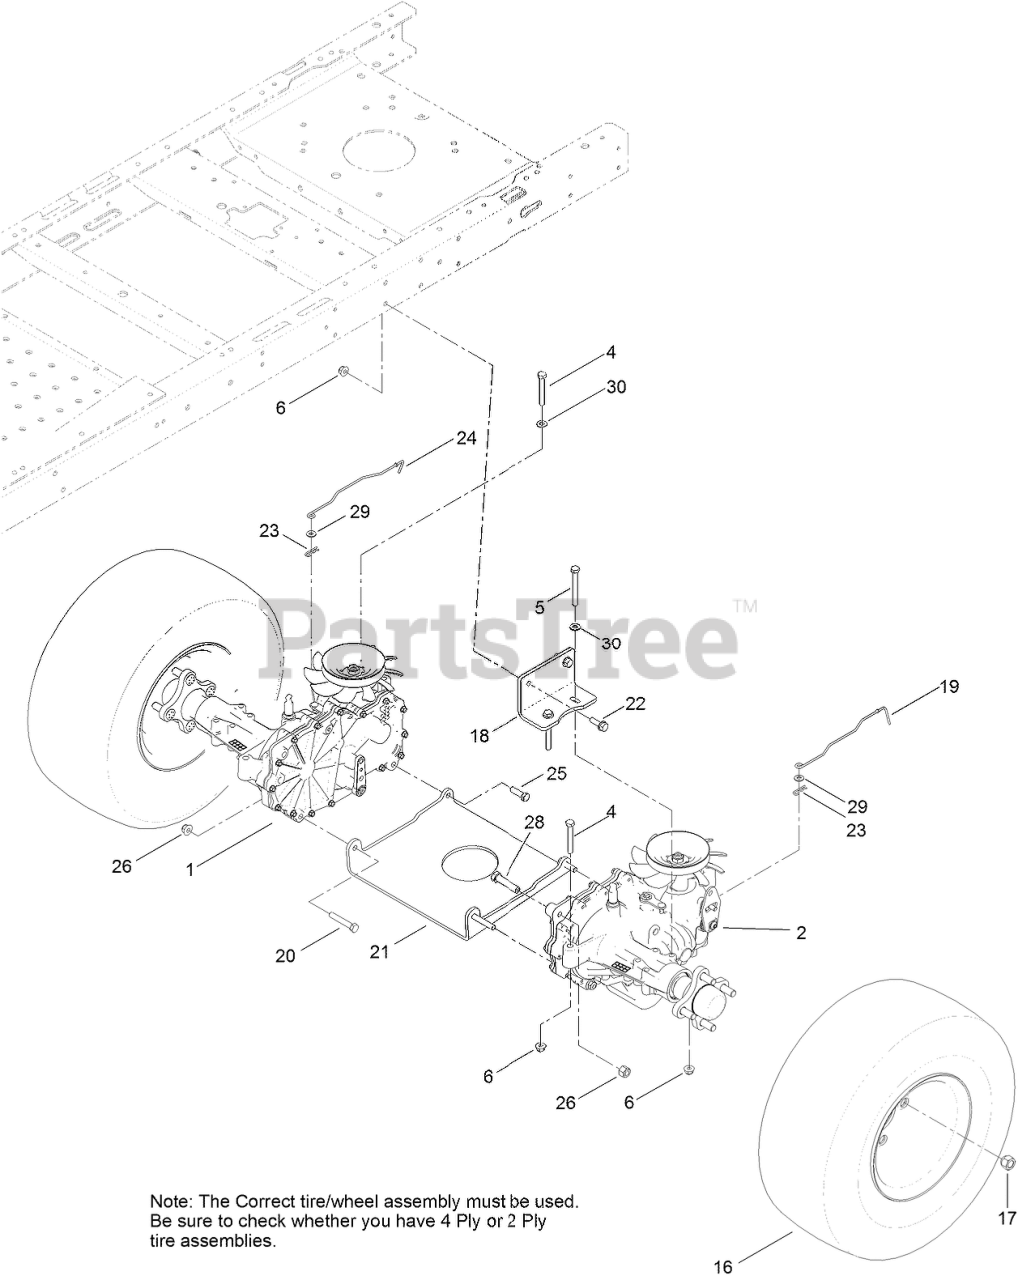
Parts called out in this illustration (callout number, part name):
1	RH HYDRO TRANSMISSION ASM
2	LH HYDRO TRANSMISSION ASM
4	SCREW-HH
5	SCREW-HH
6	NUT-HF, NI
16	4 PLY WHEEL AND TIRE ASM
16	2 PLY TIRE AND WHEEL ASM
17	NUT-LUG
18	MOUNT-HYDRO
19	ROD-BYPASS, LH
20	SCREW-HH
21	PLATE-CROSS, HYDRO
22	SCREW-HHF
24	ROD-BYPASS, RH
25	SCREW-HH
26	NUT-HF, NI
28	SCREW-HH
29	WASHER
30	WASHER-PLAIN
